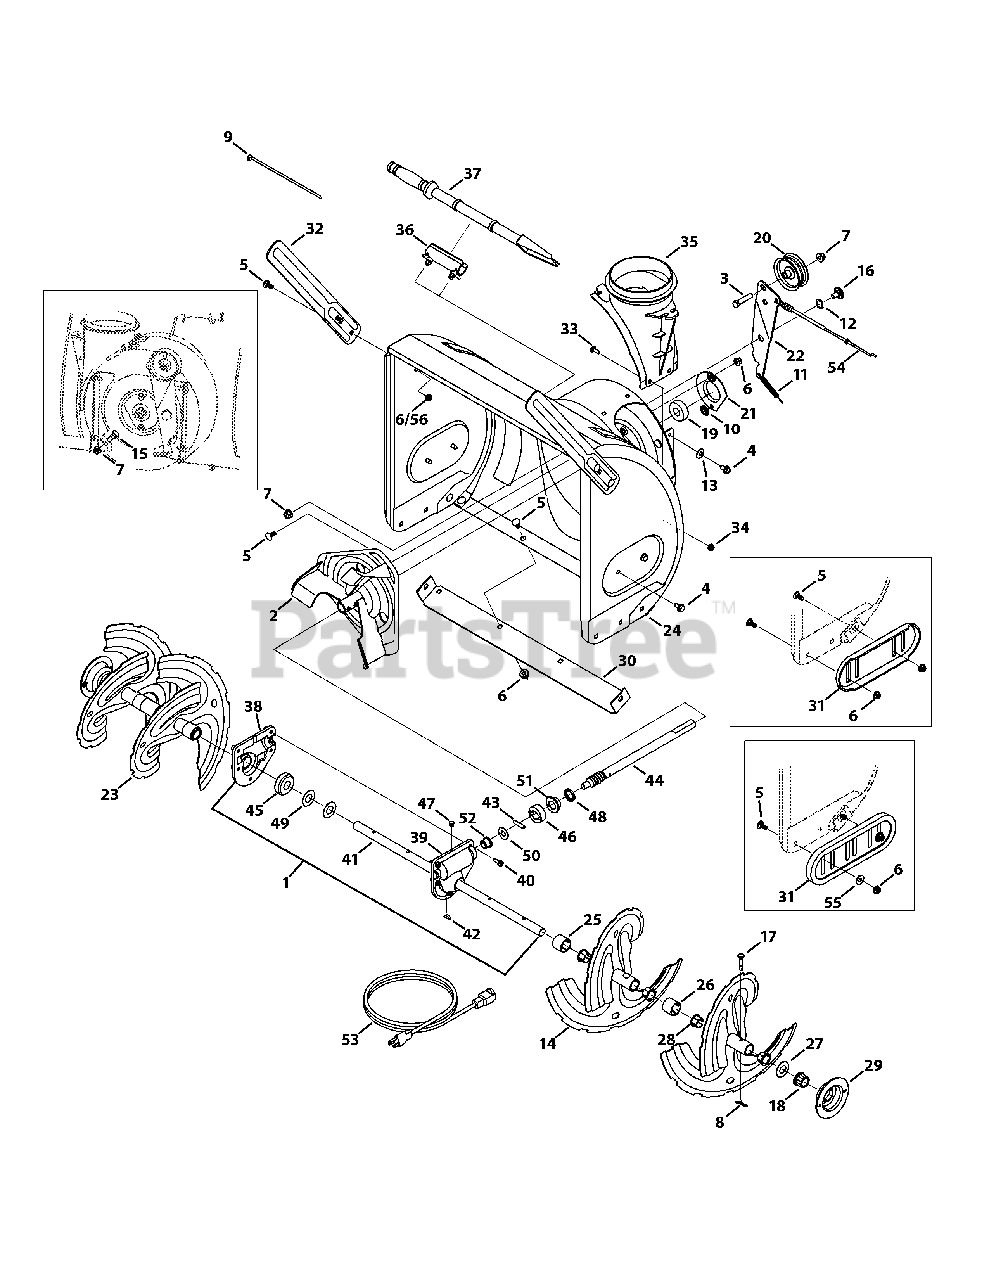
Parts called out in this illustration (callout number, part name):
1	Auger Gearbox 30", includes 38-52
2	Impeller Assembly, 12" Dia.
3	Hex Head Screw, 3/8-16 x 1.75
4	Screw, 5/16-18 x .750
5	Bolt, Carriage, 5/16-18 x .750 (Troy)
6	Nut, Flange lock, 5/16-18
7	Nut, Flange lock, 3/8-16
8	Bow-Tie Cotter Pin
9	Cable Tie, 7"
10	Nut, Push-on, .25 Dia.
11	Extension Spring, .38 x 4.59
12	Washer, Wave, .625 x .885
13	Washer, Bell, .340 x .872
14	Spiral Assembly, LH
15	Bolt, Shoulder, .496 x .336 x 3/8-16
16	Screw, Shoulder, .625 x .17 x 3/8-16
17	Shear Pin, .25 x 1.50
18	Bearing, Hex Flange, .75
19	Bearing, Ball, .75 x 1.85
20	Pulley, Idler, Flat, 2.75
21	Bearing, 1.85 ID
22	Auger Idler Bracket
23	Spiral Assembly, RH
24	Auger Housing Ass'y, Troy-Bilt, 30"
25	Spacer, 1.25 x .75 x 1.00
26	Spacer, 1.25 x .75 x 2.00
27	Washer, Flat, .76 x 1.49
28	Bushing, Flange, .800 x .910
30	Shave Plate, 2.25 x 29.66
33	Screw, Carriage, 1/4-20 x .75
34	Nut, Flange lock, 1/4-20
35	Chute Adapter
36	Clean-Out Tool Mount
37	Clean-Out Tool
38	Reducer, RH
39	Reducer, LH
40	Screw, 1/4-20 x 0.750
41	Auger Axle, 30"
42	Key, Hi-Pro, 3/16 x 5/8
43	Dowel Pin, .25 x 1.25
44	Worm Shaft, .75
45	Gear Worm, 20T
46	Collar Thrust, .756 x .600
47	Plug, 1/4 x .437
48	Oil Seal, .75 x 1.131 x .188
49	Washer, Flat, .760 x 1.50
50	Washer, Flat, .51 x 1.12
51	Bearing, Flange, .75 x 1.00 x .59
52	Bearing, Flange, .50 x .75 x .59
53	Extension Cord, 110V
54	Auger Drive Clutch Cable
55	Washer, Flat, .349 x .879 x .063
56	Wing Knob, 5/16-18
